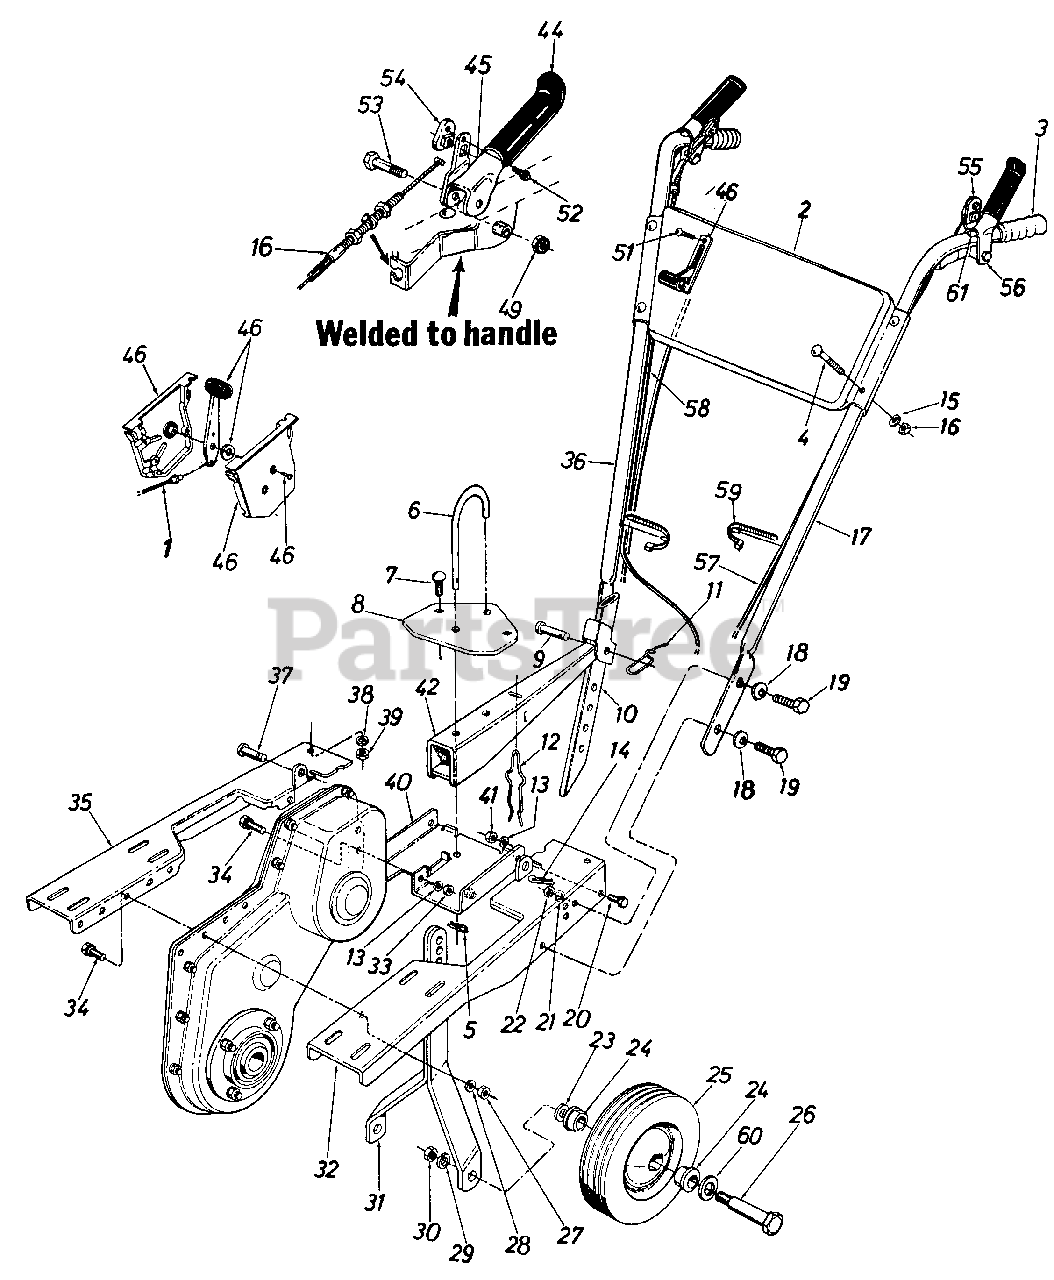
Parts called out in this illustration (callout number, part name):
1	WIRE-CONTROL
2	PANEL-HANDLE
3	GRIP-BLACK
4	BOLT-CARRIAGE 5/16-18 X 1.75
5	PIN-COTTER
6	PIN-CLEVIS .50 DIA
7	BOLT-CARRIAGE 5/16-18 X .75
8	PLATE-U CHANNEL
9	PIN-CLEVIS
10	BAR-DEPTH
11	PIN-SPRING
12	SPRING-DEPTH BAR
13	WASHER-LOCK-5/16
14	PIN-COTTER
15	WASHER-LOCK-5/16
16	NUT-HEX 5/16-18
19	SCREW-HEX 3/8-16 X 1.00
20	SCREW-HEX 5/16-18 X .75
21	WASHER-LOCK-3/8
22	NUT-HEX 3/8-16
23	WASHER-BELL .505 ID X 1.00 OD
24	BEARING-FLANGE
25	WHEEL ASSY-10 X 1.75
26	SCREW-SHLD
27	NUT-HEX 5/16-18
28	WASHER-LOCK-5/16
29	WASHER-LOCK-1/2
30	NUT-HEX INS L-1/2-20
31	BRACKET ASSY-WHL
32	CHANNEL ASSY-U-LH
33	NUT-HEX 5/16-18
34	SCREW-HEX SEMS 5/16-18 X 1.00
35	CHANNEL-ENG U
36	HANDLE ASSY-RH
37	PIN-CLEVIS
38	WASHER-LOCK-5/16
39	NUT-HEX 5/16-18
40	BRACKET ASSY-U CHANNEL
41	NUT-HEX 5/16-18
42	TAIL PIECE ASSY
45	GRIP ASSY-CLUTCH-RH
46	CONTROL BOX-THROTTLE
49	NUT-HEX INS L-3/8-24
51	SCREW-TRUSS TAP
52	SCREW-TAP
53	SCREW-HEX 3/8-24 X 2.00
54	HOLD DOWN-BARREL-RH
55	HOLD DOWN-CABLE
57	CABLE-CLUTCH CONTROL
58	CABLE-CLUTCH CONTROL
59	TIE-CABLE
60	WASHER-FL-.640ID X 1.24OD X .06HDN
61	BUMPER-RUBBER
